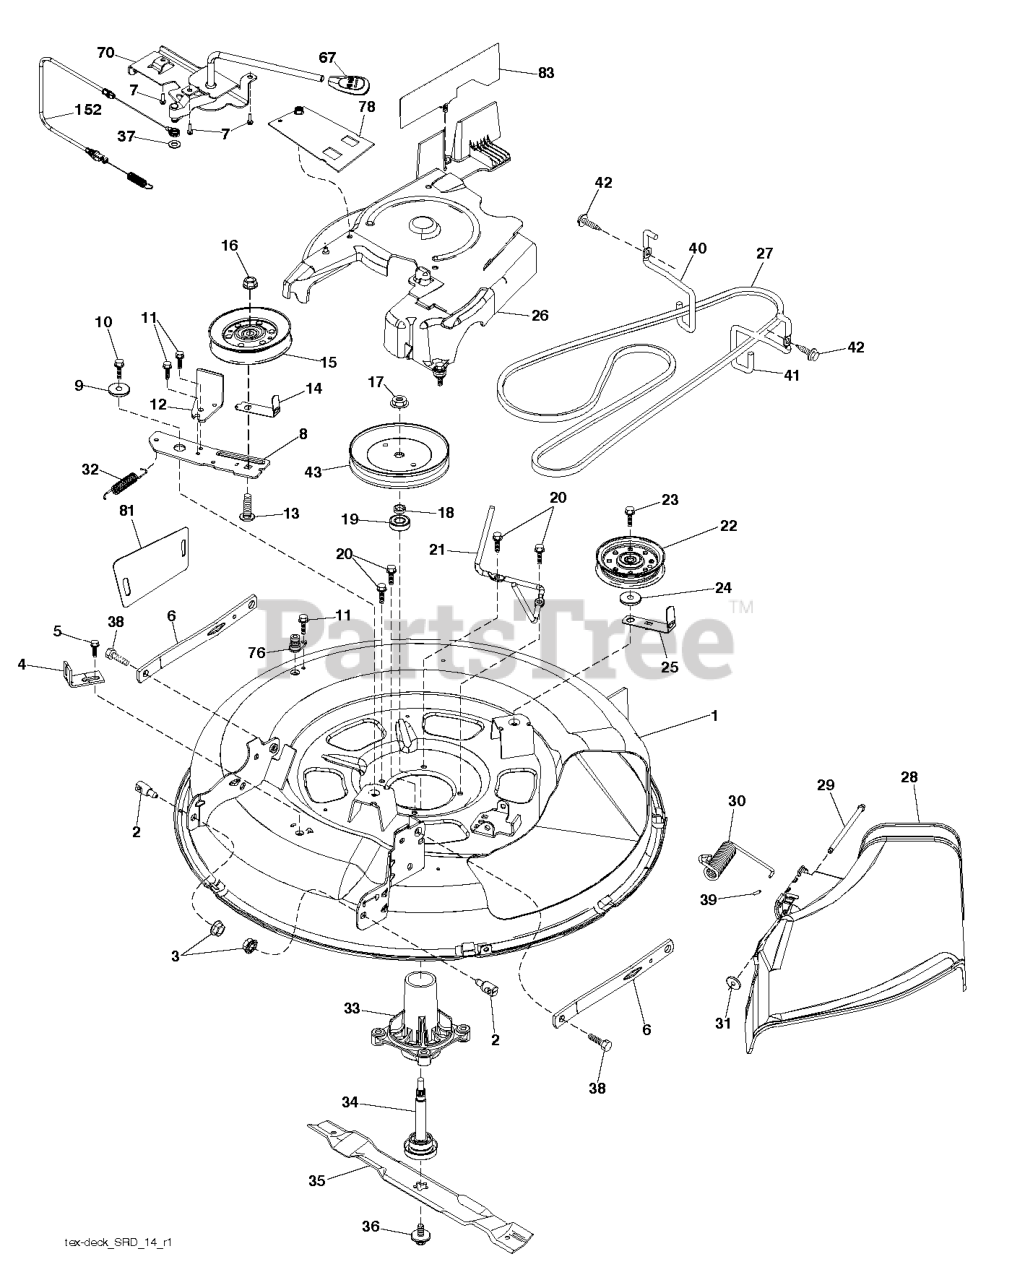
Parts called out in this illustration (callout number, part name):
1	DECK.WELDMENT.30"SRD.BLACK
2	STUD.FASTNER.W/ANTI-ROTATE
3	NUT LOCK HEX FLANGE 5/16-18
4	BRACKET.CLUTCH.CABLE
5	BOLT.5/16HEX.WHS.HD
6	ARMS.SUSP.MOWER.REAR.SRD
7	SCREW.#10 X 0.750.BOS
8	ARM.IDLER.30"SRD
9	SPACER.RETAINER
10	SCREW 3/8-16X1
11	SCREW.1/4-20X5/8
12	RP ARM.BRAKE.MOWER.38"LH.TEX
13	BOLT.3/8-16X1.50
14	KEEPER, BELT IDLER
15	PULLEY.IDLER.4.25
16	NUT LOCK FLG 3/8-16 UNC
17	NUT.FLANGE.LOCK.TOP
18	WASHER.SPACER.MANDREL
20	SCREW, WASHER HEAD
21	KEEPER.BELT.MANDREL.30"
22	PULLEY.IDLER.FLAT.UNPLATED
23	SCREW LT
24	WASHER
25	KEEPER.BELT.30"SRD
26	COVER.ASM.MANDREL.30"
27	V-BELT.DRIVE.MOWER.30"
28	SHIELD.DEFLECT.MWR.30S.BLACK
29	PIN.HINGE.30".SRD
30	SPRING.TORSION.DEFLECT
31	NUT PUSH M
32	SPRING RETURN
33	RP.HOUSING.MANDREL.4PT.
34	SHAFT.ASM.MDRL.N/GREASE.38
35	BLADE, MULCH.LRV30
36	BOLT.WASHER.ASM.7/16-2
37	WASHER
38	BOLT.SHOULDER
39	CAP-SLEEVE LT
40	KEEPER.BELT.ENGINE.LH.LT.SRD
41	KEEPER.BELT.ENGINE.RH.LT.SRD
42	SCREW, 3/8-16X3/4
43	PULLEY, MANDREL 6.5 PD
67	HANDLE.CLUTCH.CABLE.LT
70	CLUTCH.ASM.MANUAL.LT.PRED
76	PORT.WASHOUT
78	GUARD ARM CLUTCH
81	SHIELD SUSPENSION
152	CLUTCH CABLE
